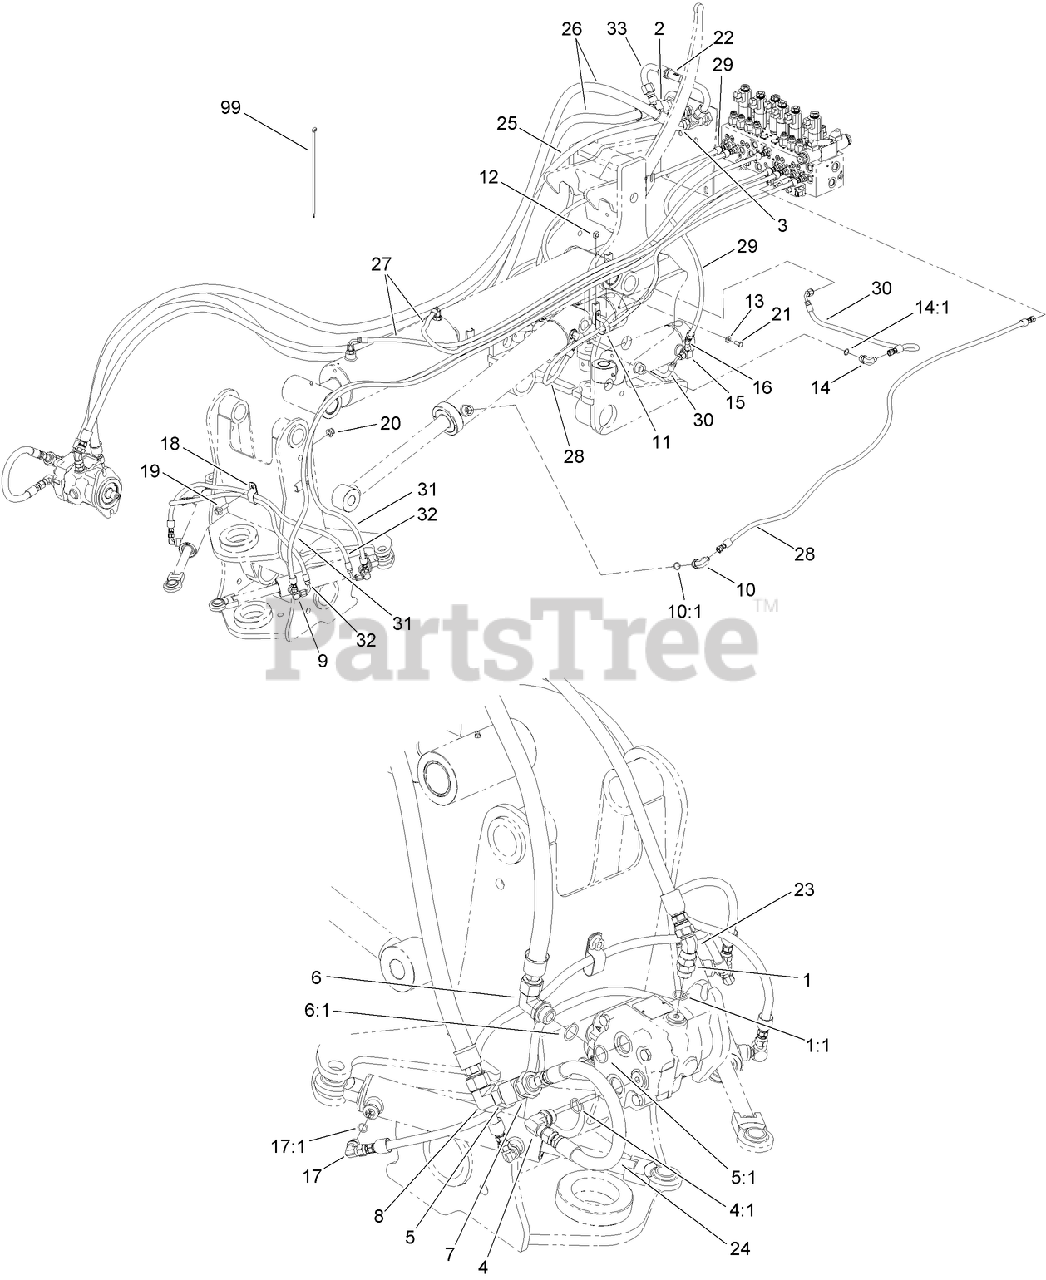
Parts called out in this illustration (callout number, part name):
1	FITTING-STRAIGHT
1:1	O-RING
2	TEE-SWIVEL
3	FITTING-ELBOW, 45 DEG
4	FITTING-90 DEG
4:1	O-RING
5	FITTING-TEE
5:1	O-RING
6	FITTING-ELBOW, 90 DEG
6:1	O-RING
7	FITTING-Restrictor
8	ELBOW-SWIVEL, 90 DEG
9	FITTING
10	FITTING-ELBOW, 90 DEG
10:1	O-RING
11	CLAMP-R
12	NUT-SQUARE
13	WASHER-FLAT
14	FITTING-ELBOW, 90 DEG
14:1	O-RING
15	TEE-SPECIAL
16	FITTING-ELBOW, 45 DEG
17	FITTING-ELBOW, 90 DEG
17:1	O-RING
18	CLAMP-DOUBLE
20	NUT-HHF, LOCK
21	SCREW-HH
22	VALVE-CHECK
23	FITTING-ELBOW, 45 DEG
24	HYD HOSE ASM, HP
25	HYD HOSE ASM, LP
26	HYD HOSE ASM, HP
27	HYD HOSE ASM, HP
28	HYD HOSE ASM, HP
29	HYD HOSE ASM, HP
30	HYD HOSE ASM, HP
31	HYD HOSE ASM, HP
32	HYD HOSE ASM, HP
33	HYD TUBE ASM, HP
99	TIE-CABLE
